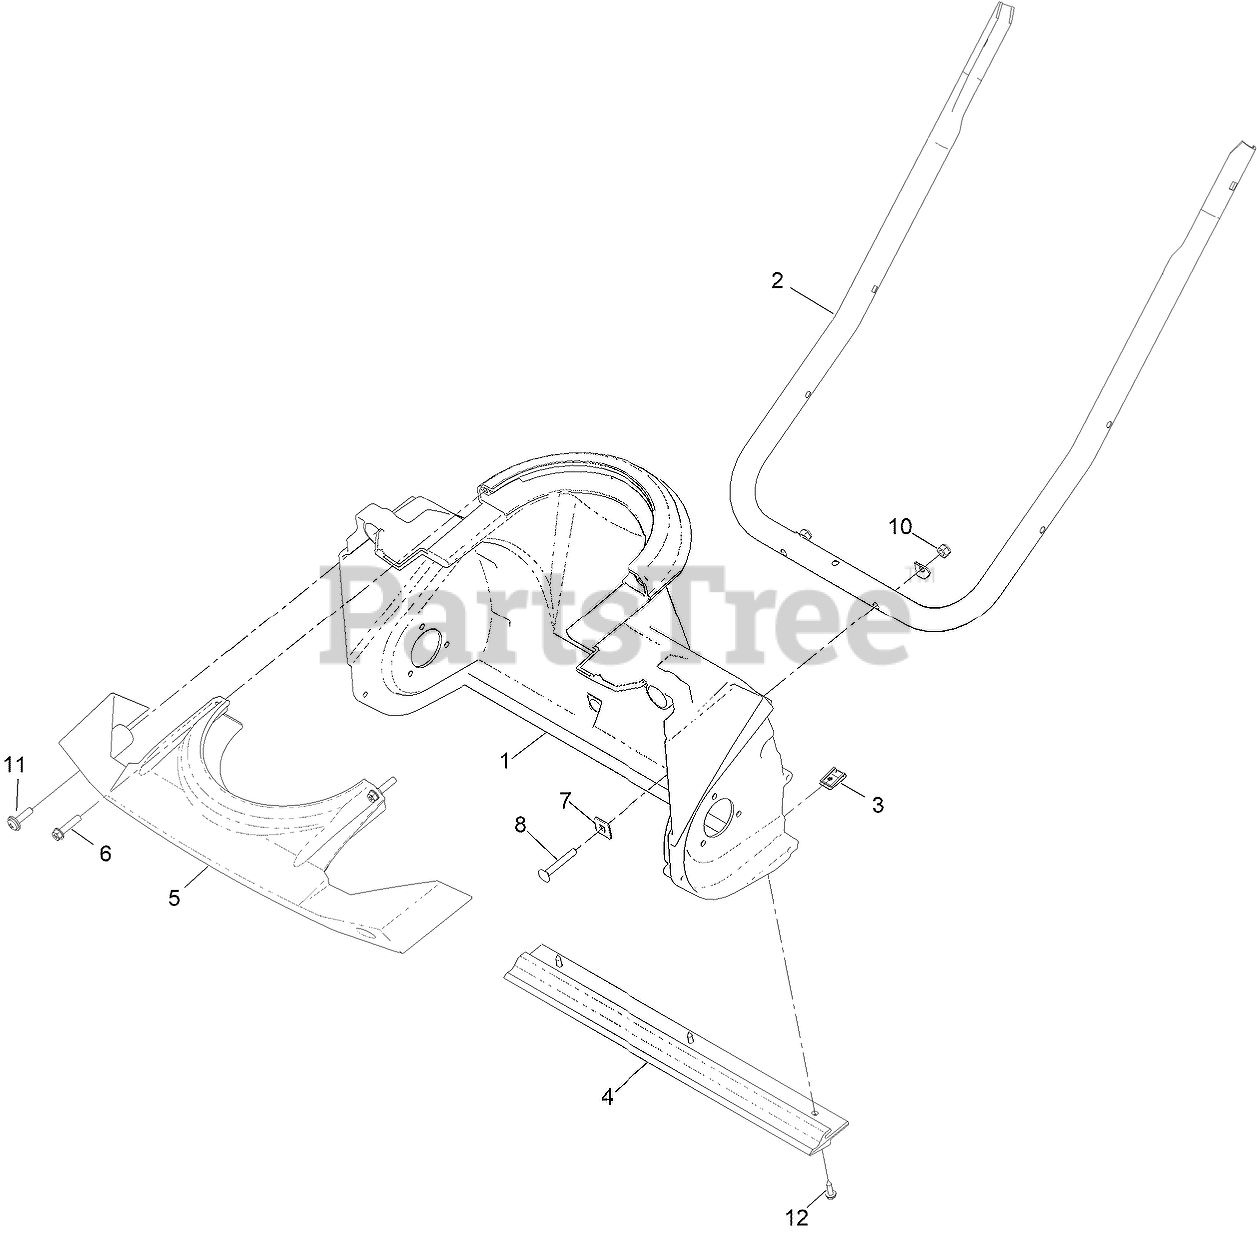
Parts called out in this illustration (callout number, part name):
1	HOUSING-ROTOR
2	HANDLE-LOWER
3	NUT-CLIP, U
4	SCRAPER
5	BUMPER-FRONT
6	SCREW-PLASTIC,HWH
7	WASHER-SQUARE
8	BOLT-CARR
10	NUT-LOCK, NI
11	SCREW-PPH, SEMS
12	SCREW-THD FORM,HWH
